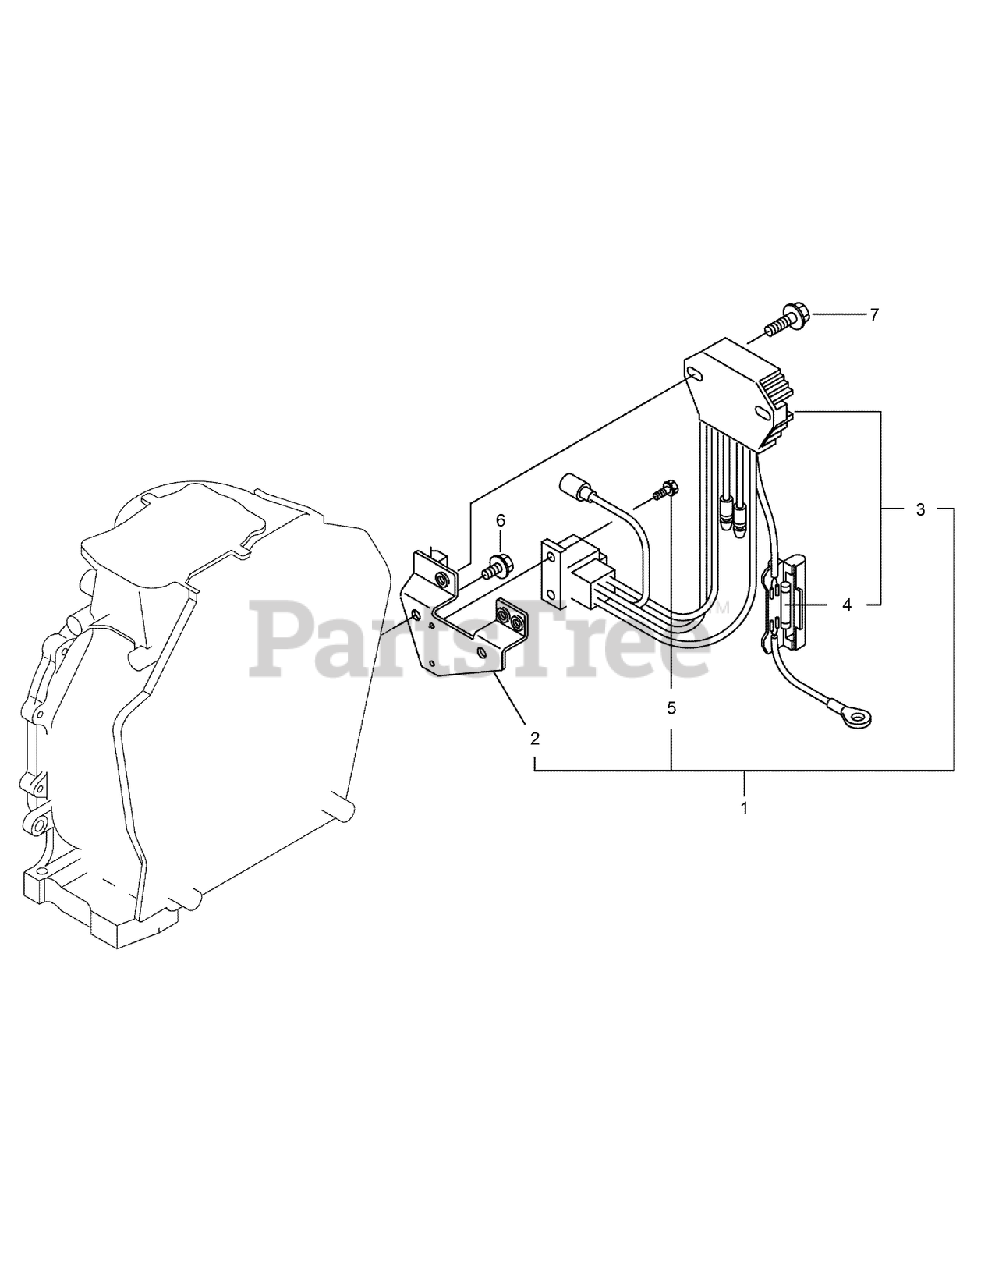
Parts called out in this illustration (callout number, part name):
1	REGULATOR AND HARNESS ASM
2	BRACKET-HARNESS
3	REGULATOR
4	FUSE-20A
